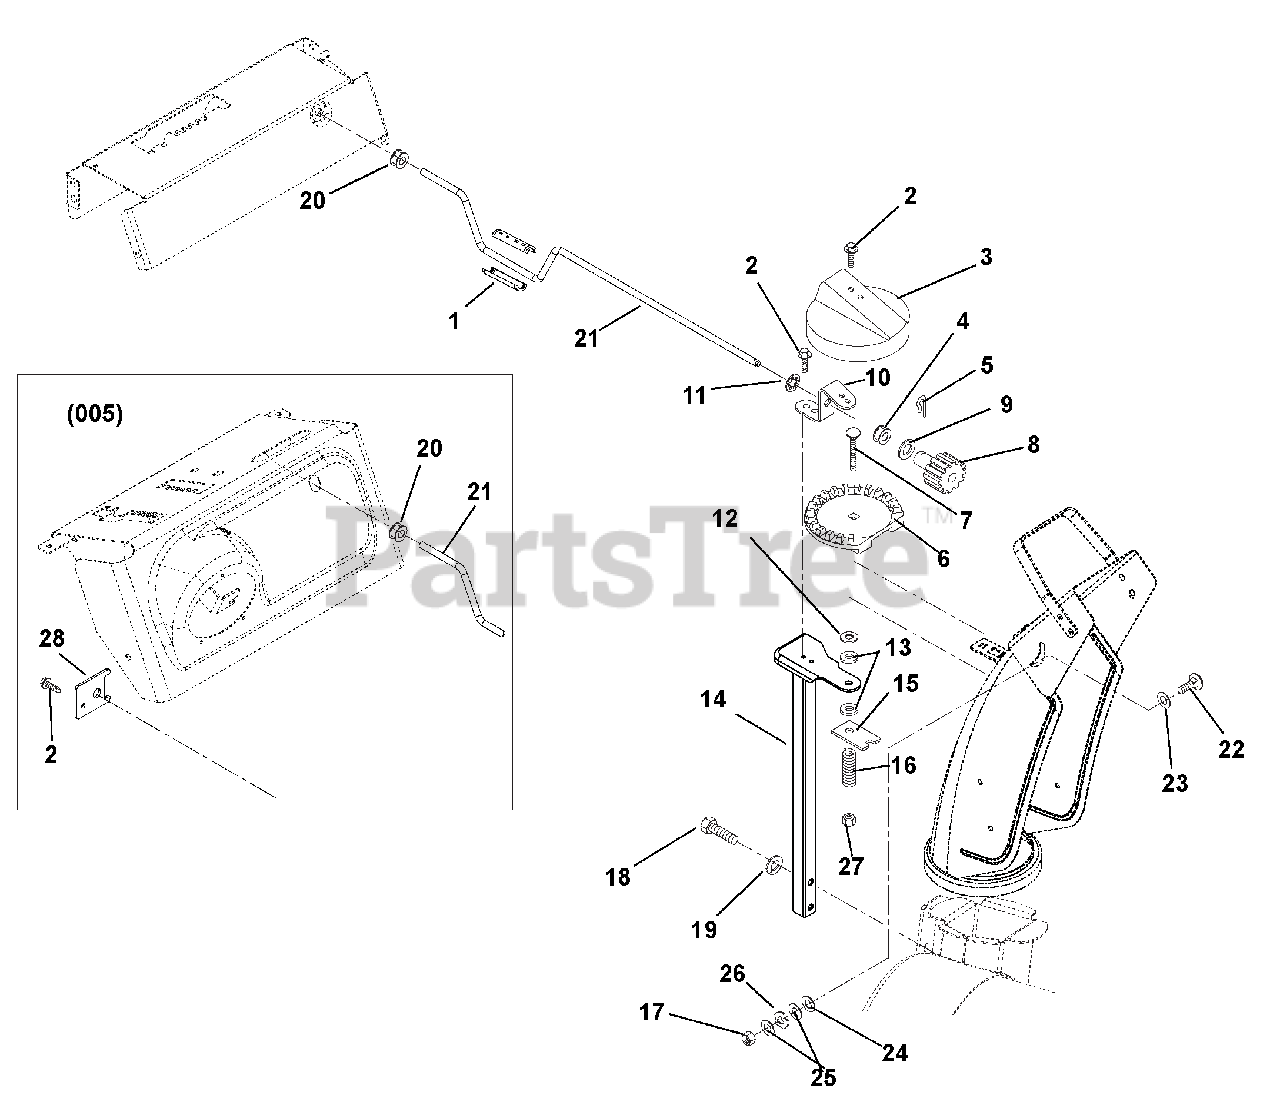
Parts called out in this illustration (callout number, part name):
1	KNOB, CRANK-SNAP
2	SCR-TAP .25-20X.50 HWH TR YWZ
3	GEAR COVER
4	BUSHING, POLYLINER-.63 SNAPIN
5	PIN, SPRING CLIP
6	CHUTE GEAR
7	@BLT-RDHDSQNK .38-16X2.50 G5YZ
8	PINION GEAR W/BRACKET
9	WSHR-THRST .625 X 1.0 X .03
10	BRACKET, PINION GEAR
11	PUSHNUT .625
12	WSHR-FL-STL .380X1.50X.062 YWZ
13	FRICTION WASHER
14	PEDESTAL, CHUTE - CRANK
15	PLATE, FRICTION
16	SG-COMP .187X.56X1.62
17	@NUT-LK-CTR .38-16 YWZC
18	@BLT-HEX .38-16X1.75 GR5 YWZC
19	@WSHR-LK .38X.094 REG YWZC
20	BUSHING, POLYLINER-.38 SNAPIN
21	ROD, CHUTE CRANK
22	@BLT-RHDSSQNK .38-16X.75 G5YZ
23	WSHR-FL-STL .52X.827X.062 YWZC
24	WSHR-FL-NY .375X.75X.060
25	@WSHR-FL-STL.406X.812X.065 YWZ
26	WAVE WASHER .390X.655X.110
27	@NUT-LK-TOP-FLG .38-16 YWZC
28	BRACKET, CHUTE CRANK
